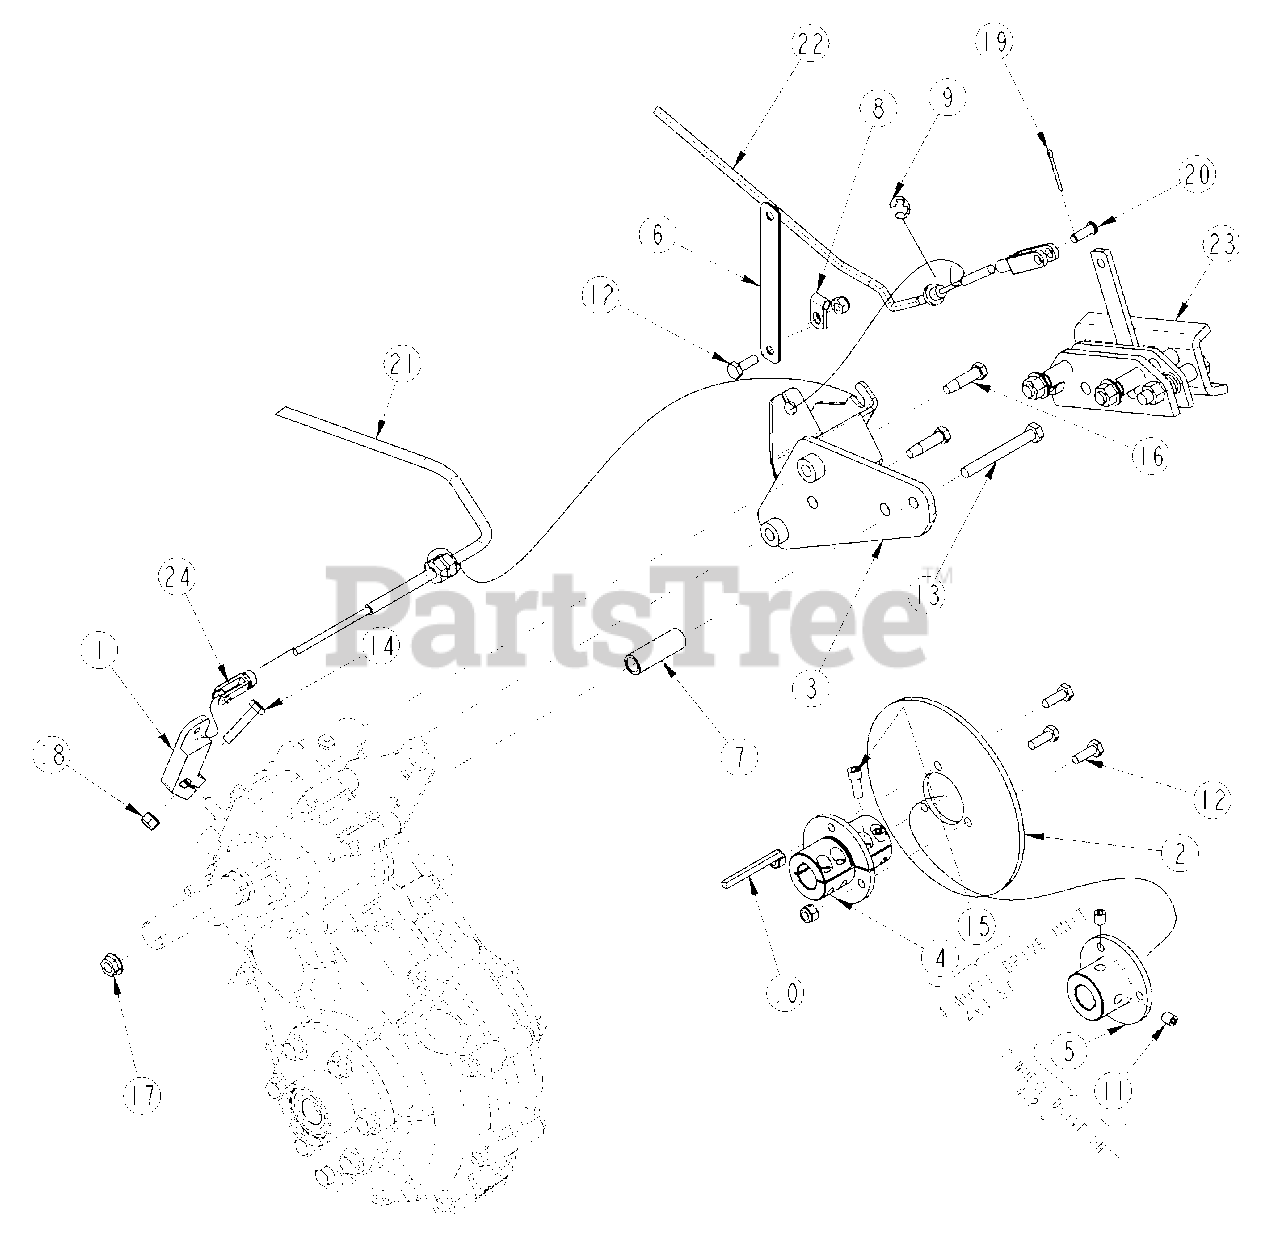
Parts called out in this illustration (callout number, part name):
1	SHIFT LEVER
2	BRAKE DISC
3	CALIPER MOUNT BRACKET
4	CLAMP COUPLING
5	BRAKE HUB ADAPTER
6	BRAKE CABLE CLIP PLATE
7	CALIPER SPACER TUBE
8	WIRING/TUBE CLIP FOR 1/4 OD
9	E RETAINING RING EXTERNAL
10	KEY .187 X .187 X 2.25 LG
11	SCREW SET 5/16-18 SKT KP X 3/8
12	HHCS 1/4-20X3/4 GR5
13	HHCS 5/16-18X2 3/4 GR5
14	HHCS 1/4-20X1 1/4 GR8
15	HSHCS 1/4-28X5/8
16	HWH 5/16-18X1 1/4 THREAD-ROLL
17	NUT HEX FLG TOP LK 5/16-18 YLW
18	NUT HEX NYLOCK 1/4-20
19	PIN COTTER 3/32 X 1 LONG
20	PIN CLEVIS 1/4 X 3/4
21	SHIFT CABLE (DASH)
22	PARK BRAKE CABLE 105.00" LG
23	BRAKE CALIPER
24	YOKE 10-32 W/ LOCK
